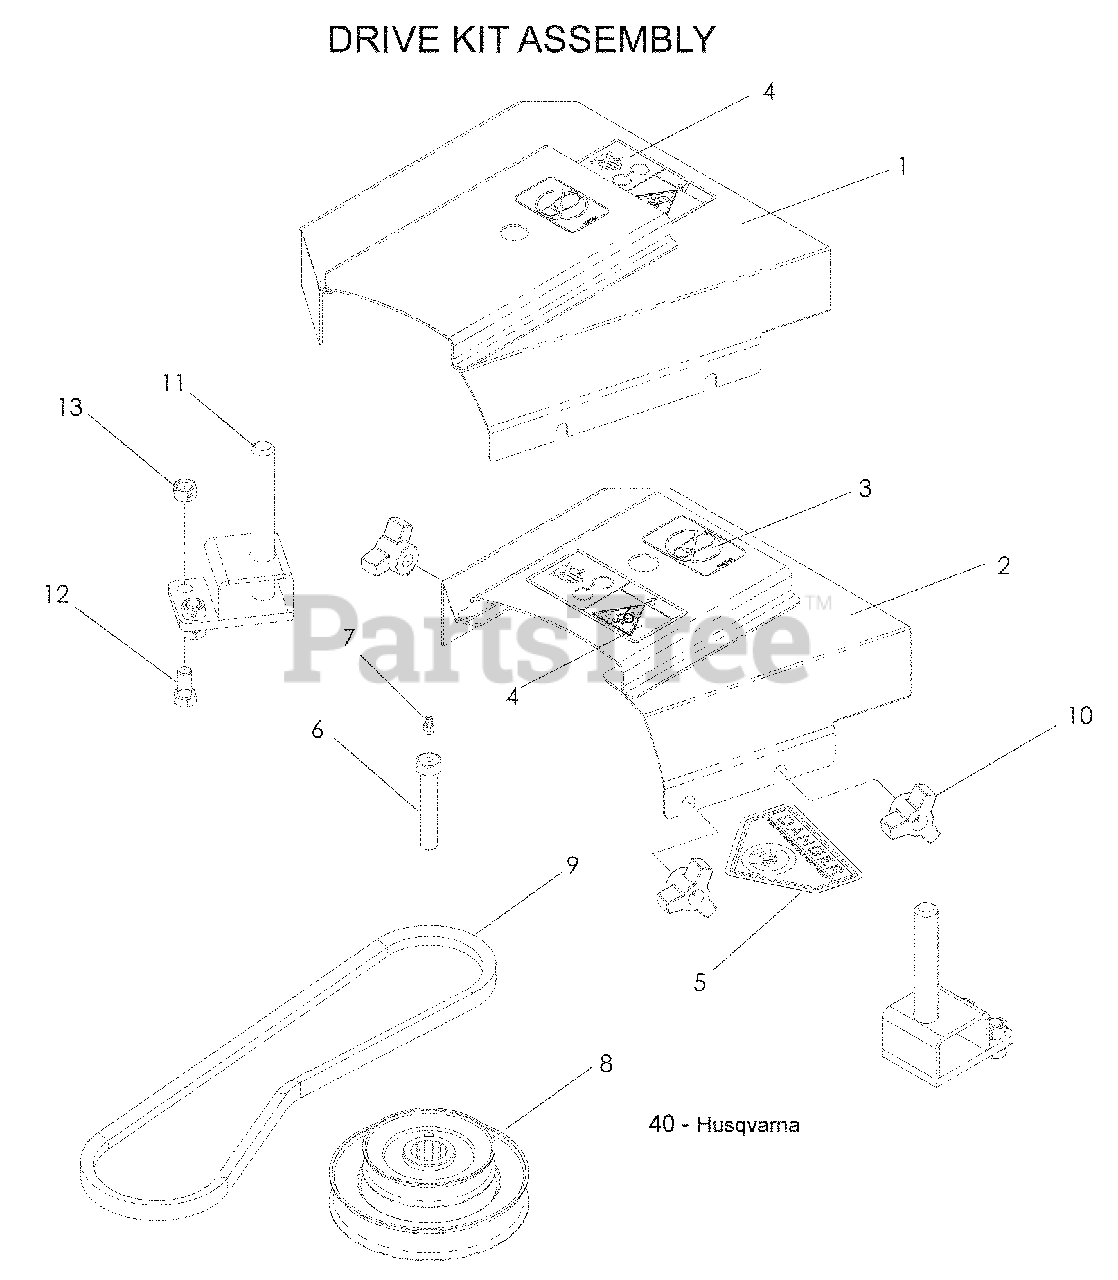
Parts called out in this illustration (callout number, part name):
1	SHIELD W/DECALS 52"
2	SHIELD W/DECALS 61"
3	DECAL, NO STEP
4	DECAL, DANGER BELT DR
5	DECAL, CPSC
6	HCS 7/16-20 x 2½ SPECIAL
7	ZERK
8	PULLEY, DBL, STACKED, 52"
10	KNOB, THREE PRONG
11	BLOWER PIN, SM
12	HCS 3/8-16 x ¾
13	NUT 3/8 -16 CENTERLOCK
